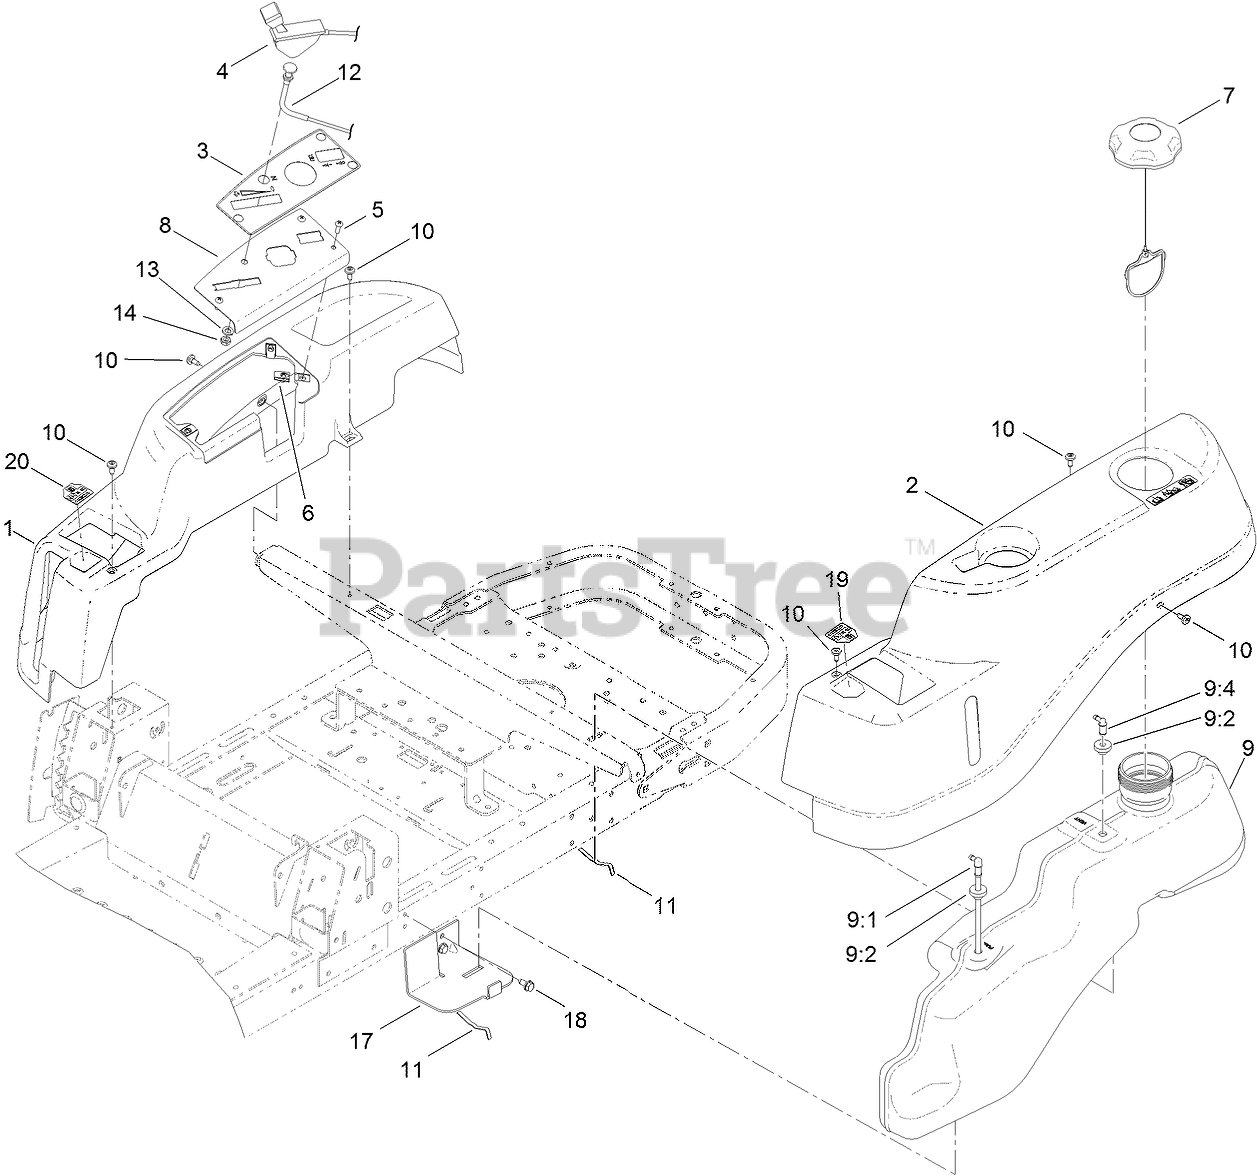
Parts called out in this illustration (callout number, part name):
1	POD-RH
2	POD-LH
3	DECAL-PANEL, CONTROL
4	CABLE-THROTTLE
5	SCREW-PRH
7	CAP-FUEL, RATCHETING
8	PLATE-CONTROL
9	FUEL TANK ASM
9:1	CONNECTOR-ELBOW, 90 DEG
9:2	BUSHING
9:4	FITTING-PLASTIC
10	SCREW-SHOULDER
11	SPRING
12	CABLE-CHOKE
13	WASHER-LOCK
14	NUT-HJ
17	SUPPORT-TANK, FRONT
18	SCREW-HWHTF
19	DECAL-CONTROL LEVER, LH
20	DECAL-CONTROL LEVER, RH
